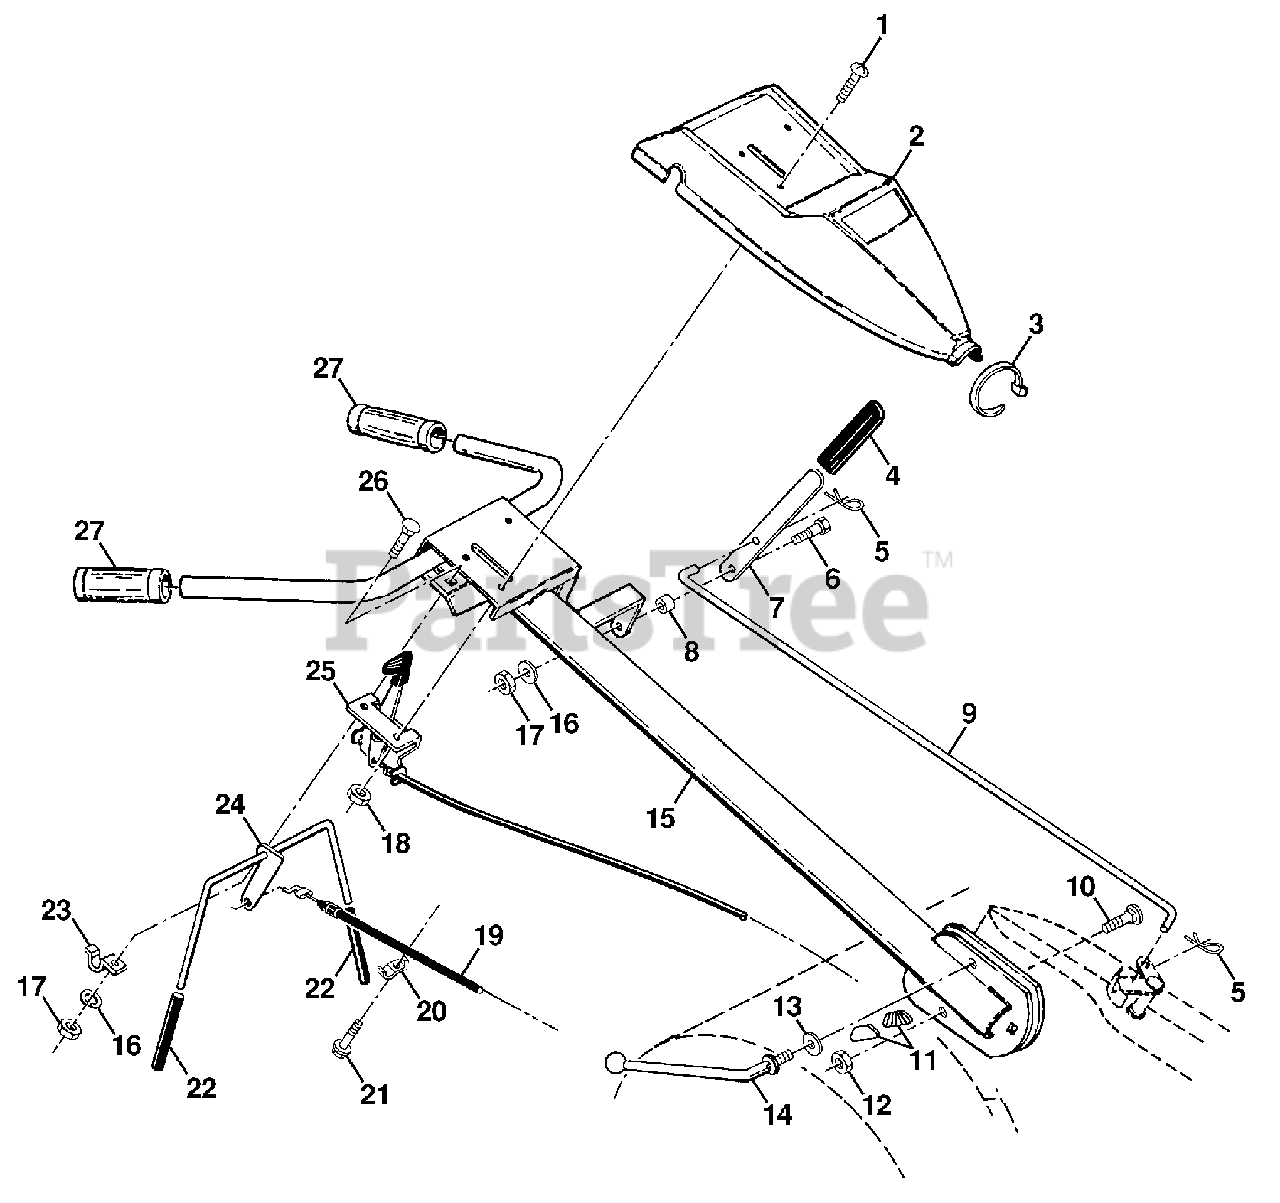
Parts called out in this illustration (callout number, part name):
1	Screw, PHD. #10-24
2	Panel, Control
3	Tie, Cable
4	Grip, Handle
5	Clip, Hairpin
6	Bolt, Shoulder
7	Handle, Shift
8	Grommet, Rubber
9	Rod, Shift
10	Bolt, Carriage 3/8-16 x 1 Gr. 5
11	Lock, Handle
12	Nut, Centerlock 3/8-16
13	Washer 13/32 x 1 x 11 Ga.
14	Lever, Lock, Handle
15	Handle
16	Washer, Lock 1/4
17	Nut, Hex 1/4-20
18	Nut, Keps #10-24 UNC
19	Cable, Clutch
21	Screw, Hex Washer Hd. Slotted #10-24 x 1/2
22	Grip, Bar, Control
23	Clamp, Bar, Control
24	Bar Assembly, Control
25	Control, Throttle
26	Bolt, Carriage 1/4-20 UNC x 1/2
27	Grip, Handle
